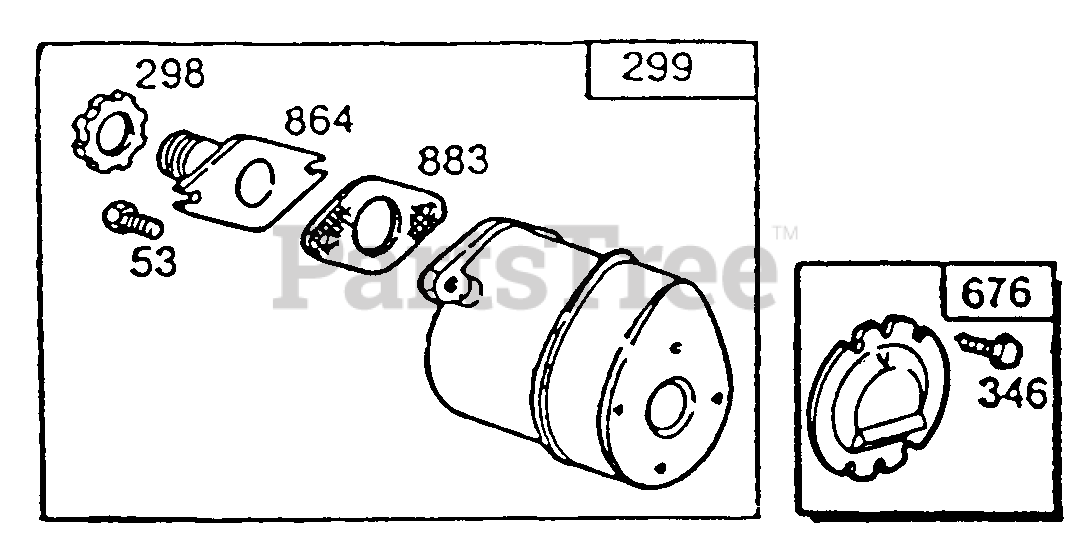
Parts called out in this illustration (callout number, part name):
53	Screw- Exhaust
298	Lock Nut- Muffler
299	Muffler- Exhaust
346	Screw- Sem
676	Deflector- Muffler
864	Adapter Ass'y.- Muffler
883	Gasket- Muffler
